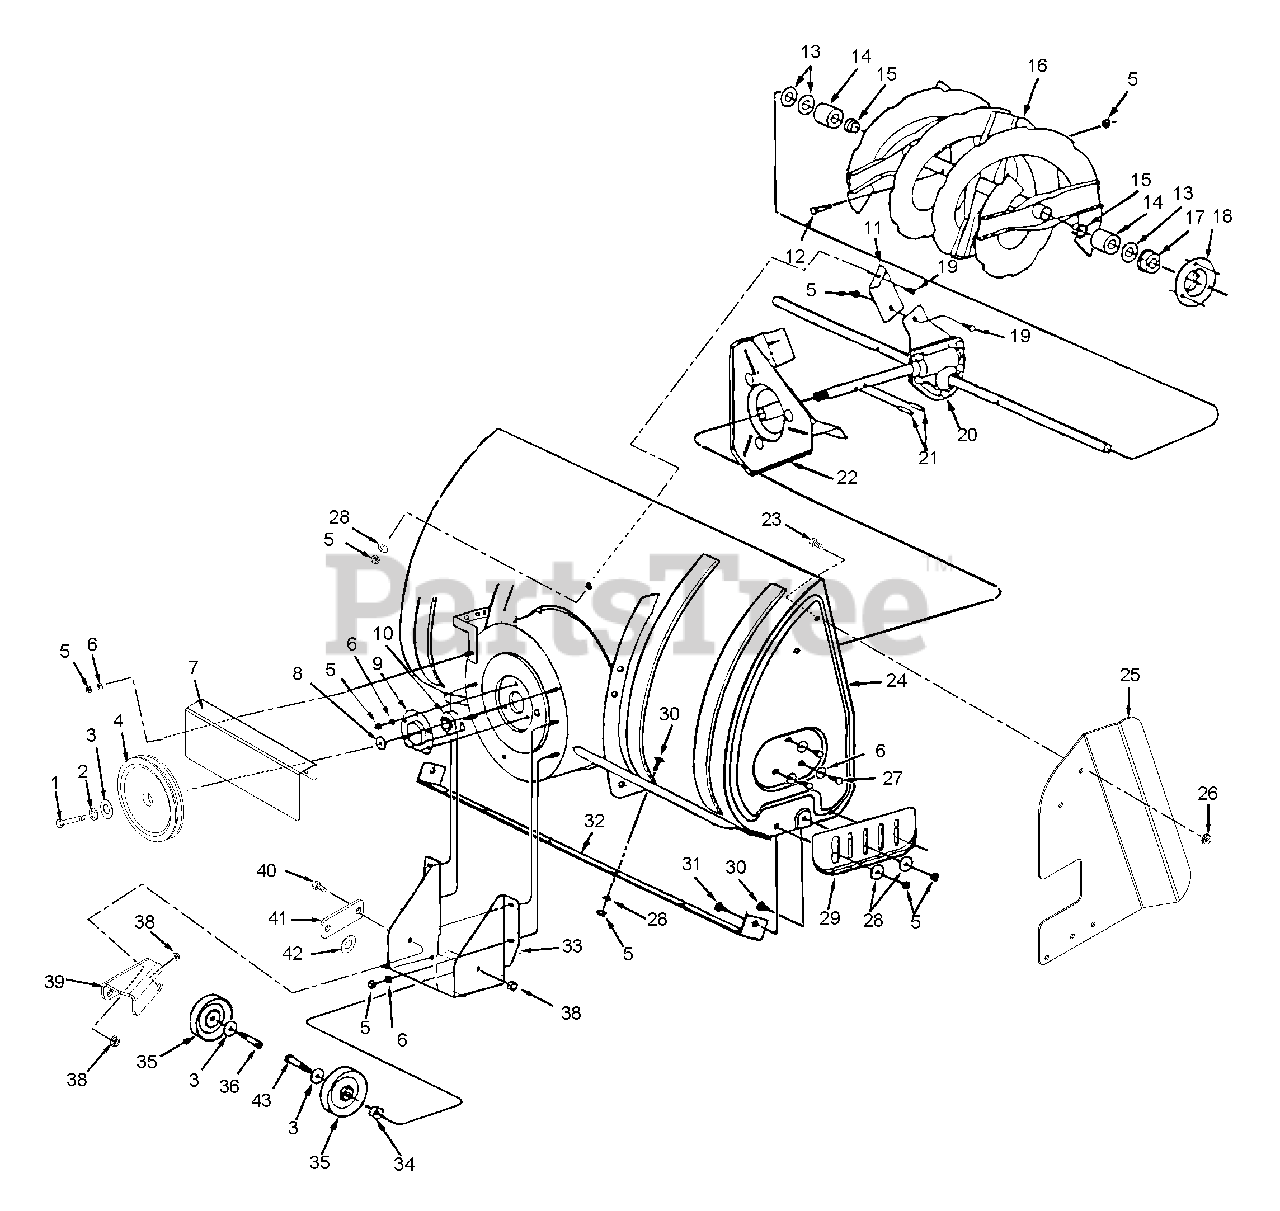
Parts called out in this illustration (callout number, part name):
1	Hex Bolt, 3/8-24 X 1
2	Lock Washer, 3/8
3	Washer
4	Pulley, V-Type
5	Hex Lock Nut, 5/16-18
6	Lock Washer 5/16
7	Finger Guard
8	Bushing
9	Housing, Bearing
10	Bearing, Ball
11	Bracket, Housing Brace
12	Bolt, Shear 5/16-18 x 1-1/2
13	Washer, .76 x 1.49 x .06
14	Spacer, .75 ID x 1.25 OD x .51
15	Bearing, Split, 3/4
16	Spiral Assembly, R.H.
17	Bearing Flange
18	Housing, Bearing
19	Hex Bolt, 5/16"-18 x 3/4"
20	Gear Assembly
21	Spiral Pin, 1/4 x 1-1/2"
22	Impeller Assembly
23	Bolt-Round Head Square Neck .31-18 x .75 Grade 5
24	Housing Assembly
25	Drift Cutter, Right Hand
26	Nut-Locking-Top-Flange .31-18
27	Bolt, Self-Tap 5/16 x 3/4"
28	Washer, 5/16
29	Skid Shoe
30	Carriage Bolt, 5/16-18 x 3/4
31	Carriage Bolt, 5/16-18 x 1
32	Scraper Plate
33	Bracket, Idler
35	Pulley, V-Type
36	Bolt-Hex .38-16 X 1.50 Grade 5
37	Spacer
38	Nut-Locking-Top-Flange .38-16
40	Bolt-Hex .38-16 X 1.00 Grade 5
41	Plate, Shim
42	Washer-Flat-Steel .406 x 1.00 x.188
43	Bolt-Hex .38-16 X 2.00 Grade 5
NA	Spiral Assembly, L. H.
